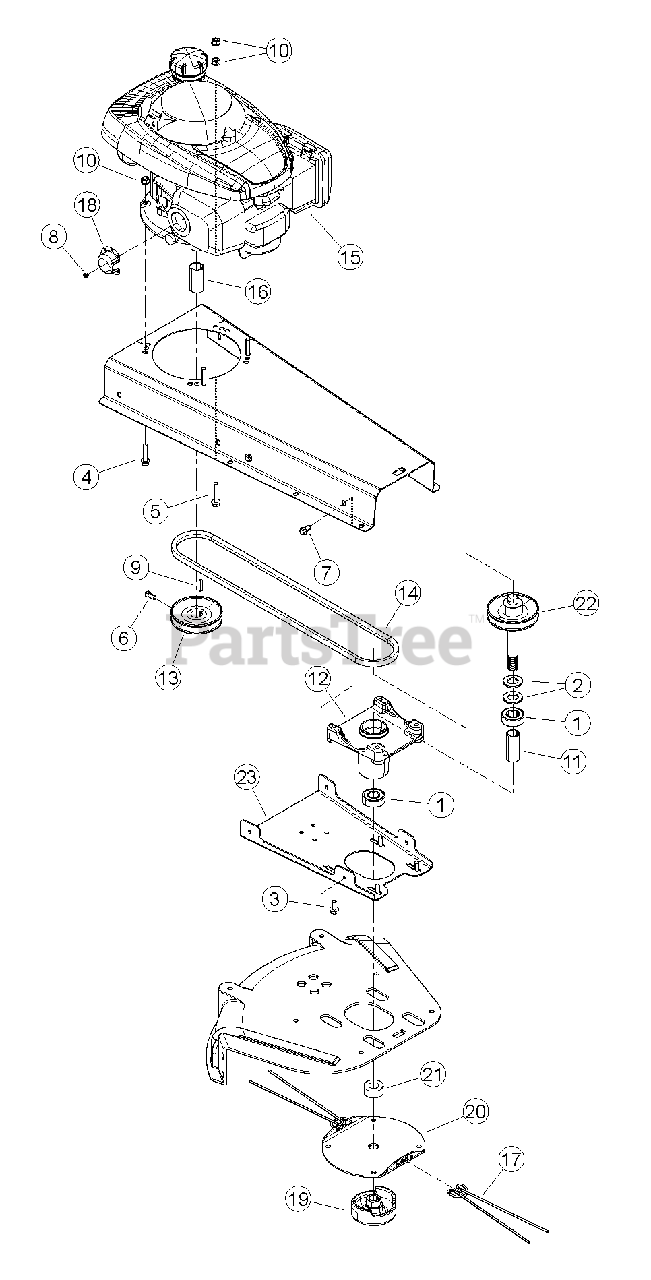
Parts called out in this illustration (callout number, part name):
1	BEARING, 3/4 BALL
2	WASHER, 3/4" SAE FLAT ZP
3	BOLT, 5/16 X 3/4 FLANGE NC
4	BOLT, 5/16 X 1-1/2 FLANGE NC
5	BOLT, 5/16 X 1-3/4 FLANGE NC
6	SCREW, 5/16-18 X 5/8 SQ HD SET
7	SCREW, 11/32-12 X 7/8 FLANGE T-AB
8	SCREW, 8-32 X 1/4 HEX THREAD CUTTING
9	KEY, 3/16" X 1.00" LG SQUARE
10	NUT, 5/16-18 NYLOCK FLANGE
11	SPACER, TRIMMER SPINDLE
12	CASTING, TRIMMER SPINDLE HUB
13	PULLEY, ENGINE 4.0 X .875 B GROOVE
14	BELT, AX48
15	ENGINE, HONDA 160CC VERTICAL (FOR SERVICE SEE ENGINE OWNER'S MANUAL OR NEAREST HONDA INDUSTRIAL ENGINE DEALER)
16	SPACER, HONDA 1-1/16 OD X 14 GA X 2.134
17	STRING, 20" X .155 DIA. CROSS-FIRE
18	DEFLECTOR, HONDA GCV 160
19	MOWBALL, CAST TRIMMER PAINTED
20	DISK, TRIMMER HEAD
21	SPACER, TRIMMER HEAD
22	WELDMENT, SPINDLE HW MODELS
23	PLATE, SPINDLE CASTING MOUNT
